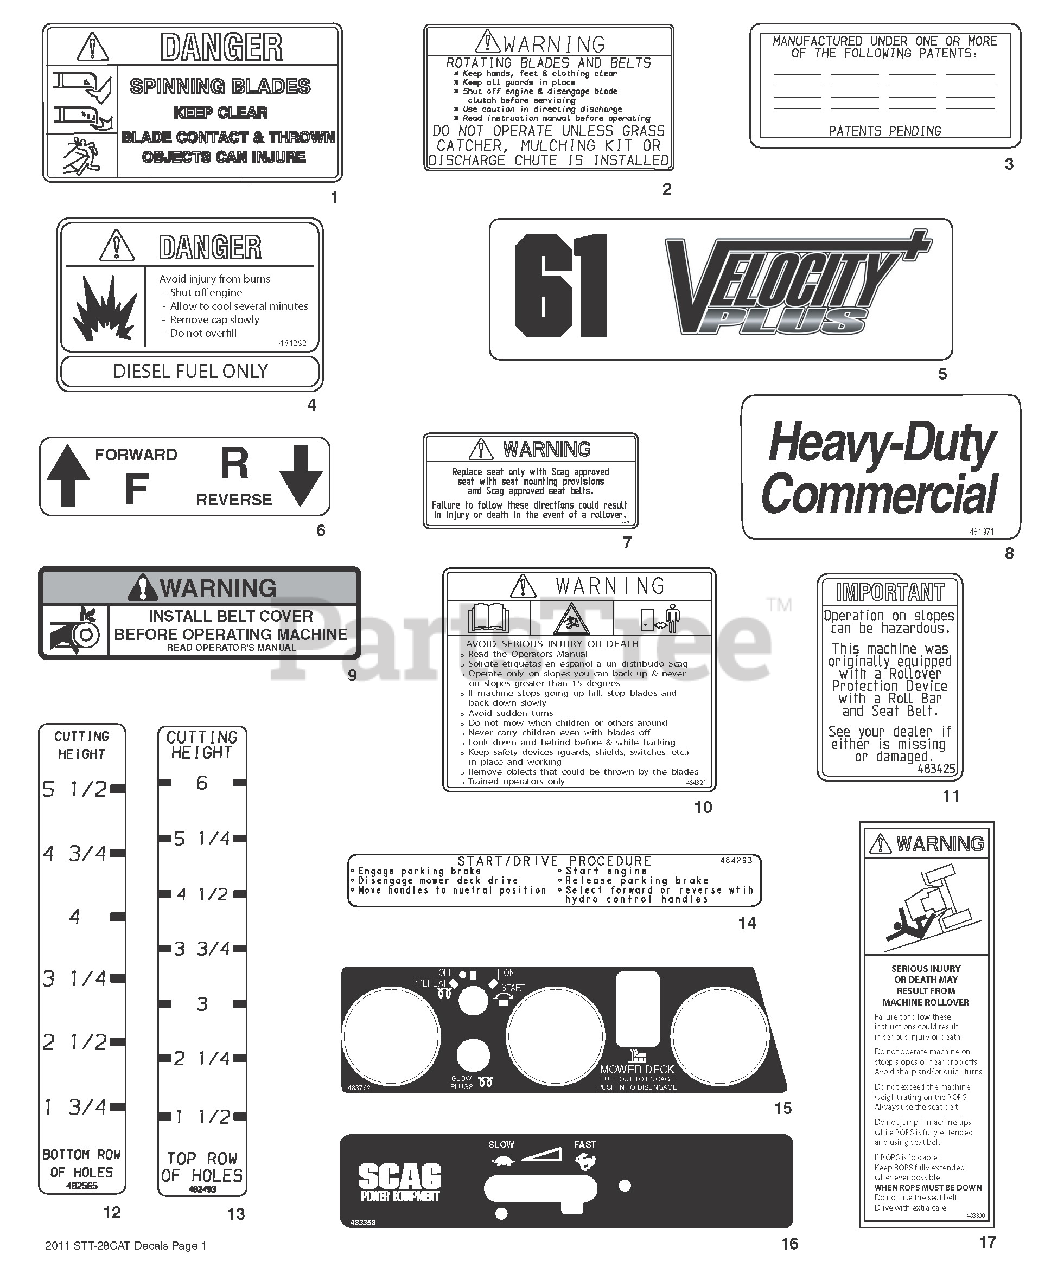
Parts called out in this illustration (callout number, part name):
1	Decal, Danger-Spinning Blades
2	Decal, Warning-Rotating Blades
3	Decal, Patents
4	Decal, Fuel Tank
5	Decal, 61" Velocity Plus
5	Decal, 72" Velocity Plus
6	Decal, Traction Control
7	Decal, Seat Replacement
8	Decal, Heavy Duty Commercial
9	Decal, Belt Cover
10	Decal, Warning
11	Decal, ROPS
12	Decal, Cutting Height - Lower
13	Decal, Cutting Height - Upper
14	Decal, Start/Drive Procedure
15	Decal, Instrument Panel
16	Decal, Instrument Panel
17	Decal, ROPS Warning
